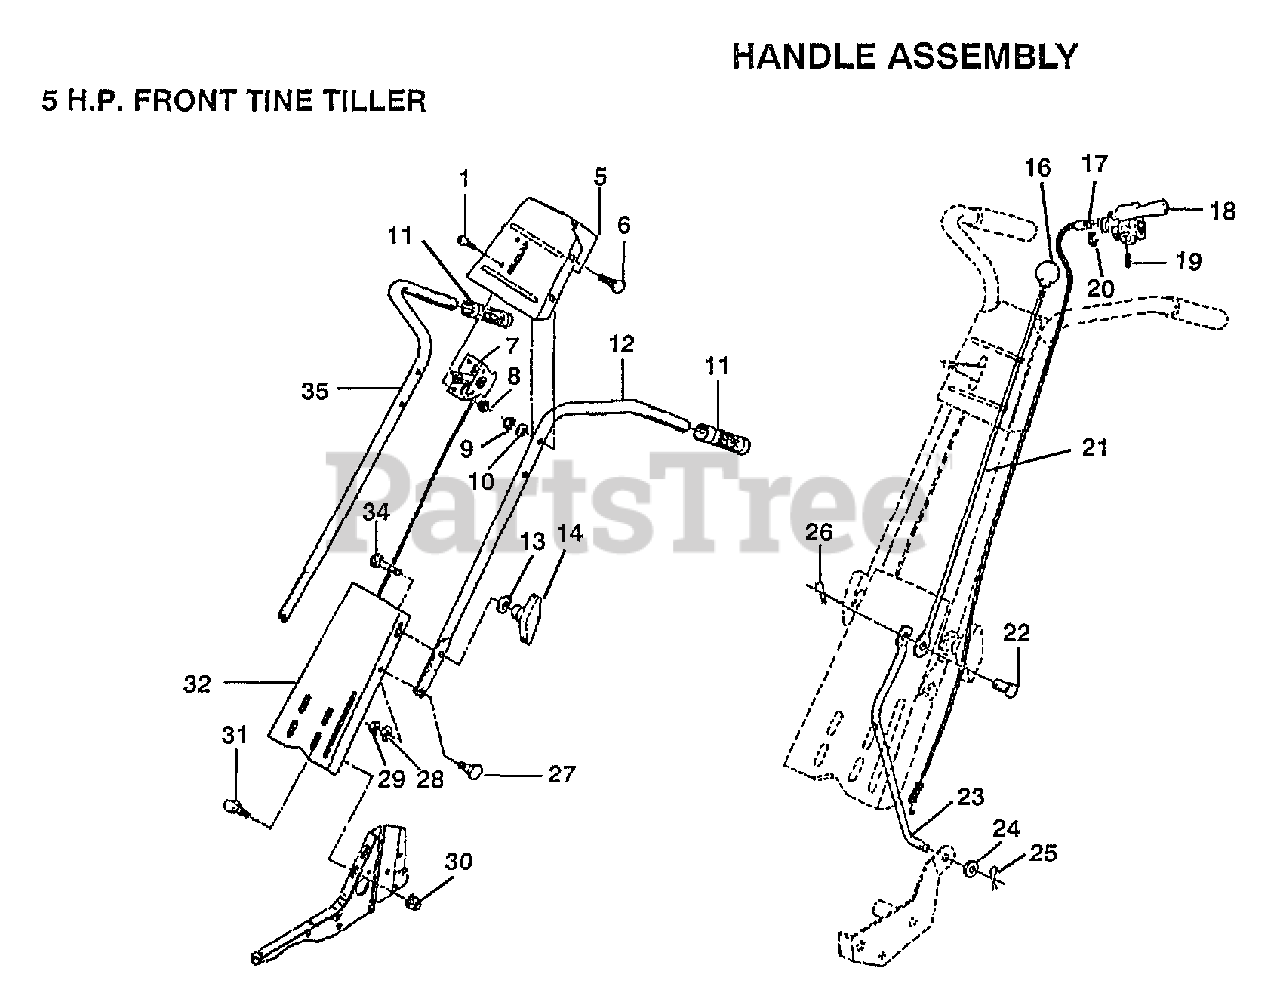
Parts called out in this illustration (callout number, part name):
1	SCREW
5	BRKT HDLE TI
6	BOLT
10	WASHER
13	WASHER
17	CABLE CLUTCH T
18	CONTROL LEVER TI
19	SCREW
20	E-RING
21	ROD REVERSE TI
22	RIVET.RD.HD.DRILL
23	REVERSE ROD TI
24	WASHER
25	COTTER PIN
28	LOCKWASHER
29	NUT.HEX.5/16-18
30	NUT
31	BOLT
34	BOLT
